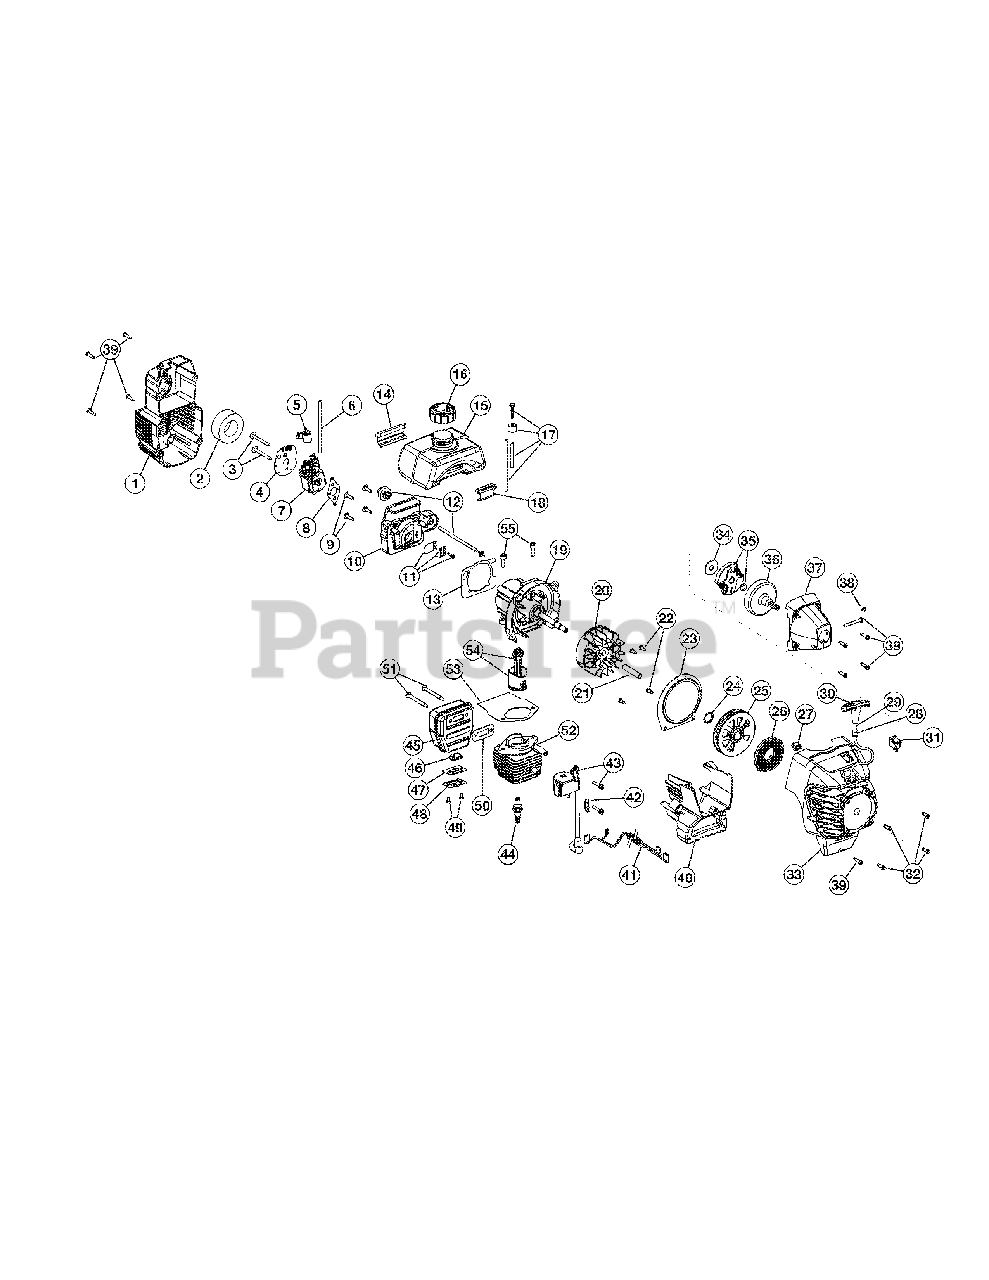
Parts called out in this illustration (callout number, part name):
1	Air Cleaner Cover Assembly (includes 2 & 39)
2	Air Cleaner Filter
3	Carburetor Mounting Screw Assembly
5	Choke Plate
5	Choke Lever
6	Fuel Return Line
7	Carburetor Assembly (includes 8 & 17)
8	Carburetor Gasket
9	Carb Mount Screw
10	Carb Mount Assembly (includes 9, 11 & 13)
11	Reed Assembly
12	Primer and Hose Assembly
13	Carburetor Mount Gasket
14	Rear Mounting Pad
15	Fuel Tank Assembly (includes 6, 16 & 17)
16	Fuel Cap Assembly
17	Fuel Line Assembly
18	Front Mounting Pad
19	Crank Case Service Assembly (includes 9)
20	Flywheel Assembly
22	Pressure Plate Screw
23	Pressure Plate
24	Pulley Retainer
25	Recoil Pulley Assembly
26	Recoil Spring
27	Rope Guide Retainer
28	Rope Guide
30	Pull Handle
32	Housing Screw
33	Starter Housing Assembly (includes 22-32 & 39)
34	Clutch Washer
35	Clutch Rotor Assembly
36	Clutch Drum Assembly
37	Clutch Cover Assembly (includes 38 & 39)
38	Anti-Rotation Screw
39	Cover Screw
40	Shroud Extension & Stand (includes 39)
41	Wire Leads and Sleeve
42	Ground Tab
43	Module Assembly
44	Spark Plug
45	Muffler Assembly (includes 46-51)
46	Spark Arrestor Screen
47	Spark Arrestor Plate
48	Spark Arrestor Hood
49	Spark Arrestor Screw
50	Exhaust Gasket
51	Muffler Mounting Bolt Assembly
52	Cylinder Assembly (includes 53 & 54)
53	Cylinder Gasket
54	Piston and Rod Assembly
55	Cylinder Bolt
